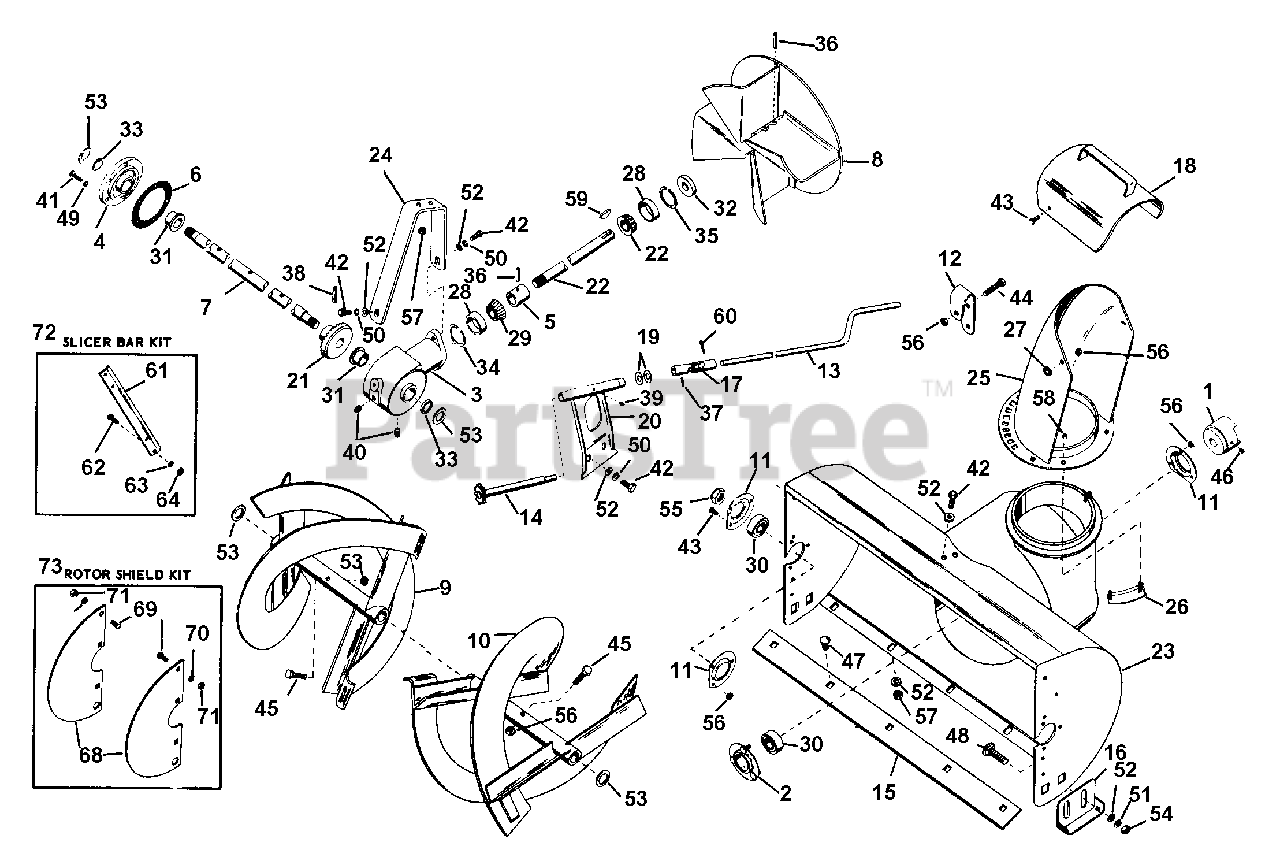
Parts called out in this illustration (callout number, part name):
1	TILLER DRIVING JAW
2	BEARING FLANGE
3	GEAR CS
4	FLNGE GEAR CS
5	BEARING SPACER
7	FRONT GEAR SHFT
9	R H RAKE
10	L H RAKE
11	BEARING FLANGE
12	ROD HANGAR
13	CHUTE CNTL CRANK
14	CONTROL SPROCKET
15	SCRAPER BLADE 24"
16	RUNNER
17	UNIVERSAL JOINT
18	DEFLECTOR
19	WAVE WASHER .515 X 1.00 X .125
20	CHUTE CNTL SPRT
21	HELICON GEAR
22	PINION
23	BLOW HSG
24	GEAR CS SPRT
25	DISCHARGE CHUTE
26	CHUTE CLAMP
27	RUBBER WASHER
28	BRG-CUP 1.781X.475
29	BRG-CONE .750X.61
30	BRG-BALL .750X1.750X.50
31	BSHG-FLG .875X1.125X.625X1.500
32	SEAL .750X1.781X.250
33	SEAL .875X1.125X.125
34	RG-RTNG INT 1.781 HSG X.062
35	SNAP RING KIT
36	PIN-ROLL .250X1.25
37	PIN-ROLL .125X1.00
38	PIN-ROLL .313X1.38
39	ZERK FITTING
40	PIPE PLUG
41	BLT-HEX .25-20X.75 PL GR2
42	BLT-HEX .31-18X.63 PL GR 2
43	BLT-HEX .31-18X.63 PL GR 2
44	BLT-HEX .38-16X1.25 PL GR 2
45	SHEAR BOLT & NUT SERVICE ASSEM
46	SCR-SET .38-16X.50 SKHCUP OH
47	BLT-RDHDSQSHNK .31-18X.50 YZ
48	BLT-RDHDSQNK .38-16X.75 SHT PL
49	WSHR-LK .250X.077 HVY PL
50	WSHR-LK .312X.097 PL HVY
51	WSHR-LK .375X.115 HVY PL
52	WSHR-FL-STL .38X.875X.083 PL
53	WSHR-FL-STL .531X1.062X.095 PL
54	NUT-JAM .375-16 PL
55	NUT-LK-CTR .75-16 PL
56	NUT-LK-CTR .250-20 PL
57	NUT-LK .312-18 GR A PL
58	NUT-KEPS 10-24 PL
59	KEY-WDRF .188X.875X.375 SAE11
60	PIN-COTR .09X.75 PL
61	CUTTER BAR
62	BLT-RDHDSQNK .31-18X.75 GR5 PL
63	WSHR-LK .312X.097 PL HVY
64	NUT-JAM .375-16 PL
69	BLT-RDHDSQNK .31-18X.75 GR5 PL
70	WSHR-LK .312X.097 PL HVY
71	NUT-JAM .375-16 PL
72	Slicer Bar Kit(Inc. 61,62,63,64)
73	Sno-Rotor Shield Kit(Inc. 68,69,70,71)
